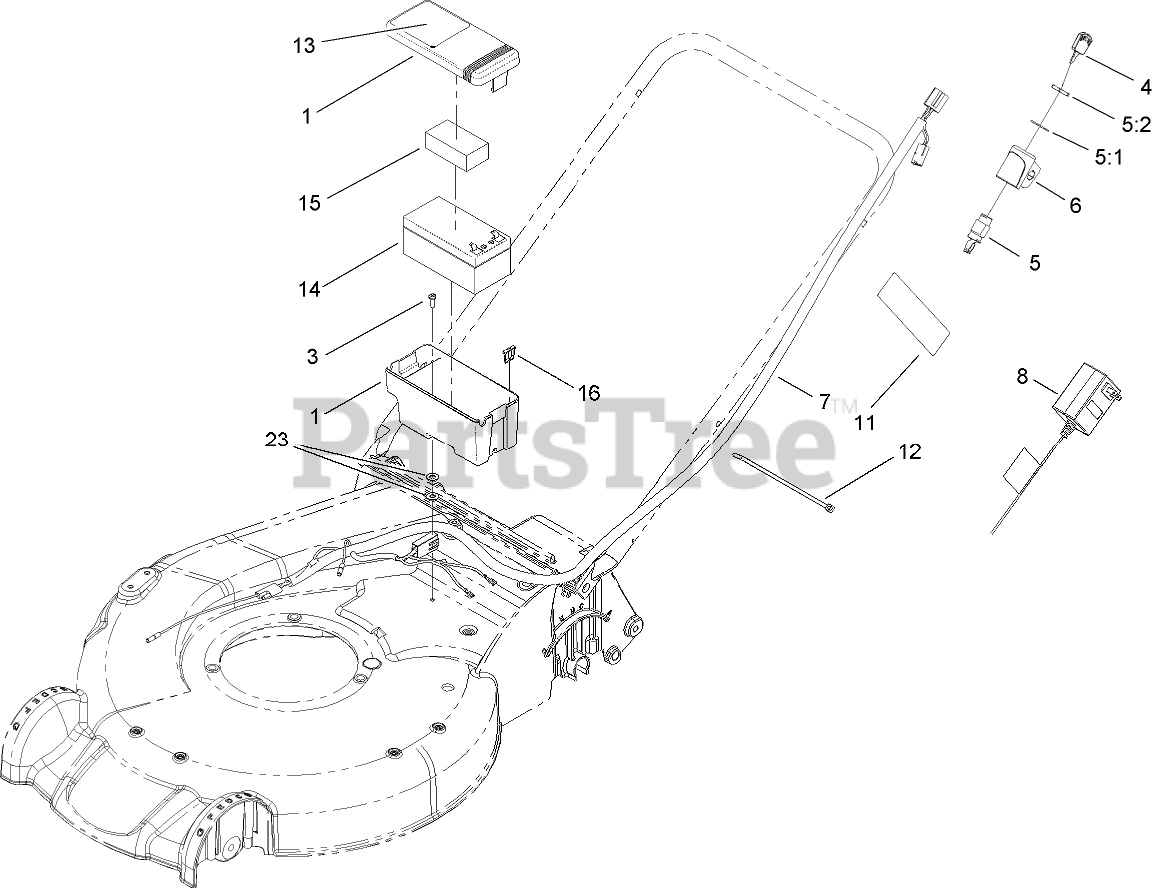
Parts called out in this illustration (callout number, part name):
1	BATTERY BOX ASM
5	STARTER SWITCH ASM
5:1	WASHER-TOOTH, INTERNAL
5:2	NUT-HH
6	MOUNT-SWITCH
7	HARNESS-WIRE
8	CHARGER-12 VOLT
11	DECAL-WARNING
12	TIE-CABLE
13	DECAL-INSTRUCTIONAL
14	BATTERY-WET
15	FOAM-BATTERY, TOP
16	FUSE-40 AMP
23	WASHER-FLAT
